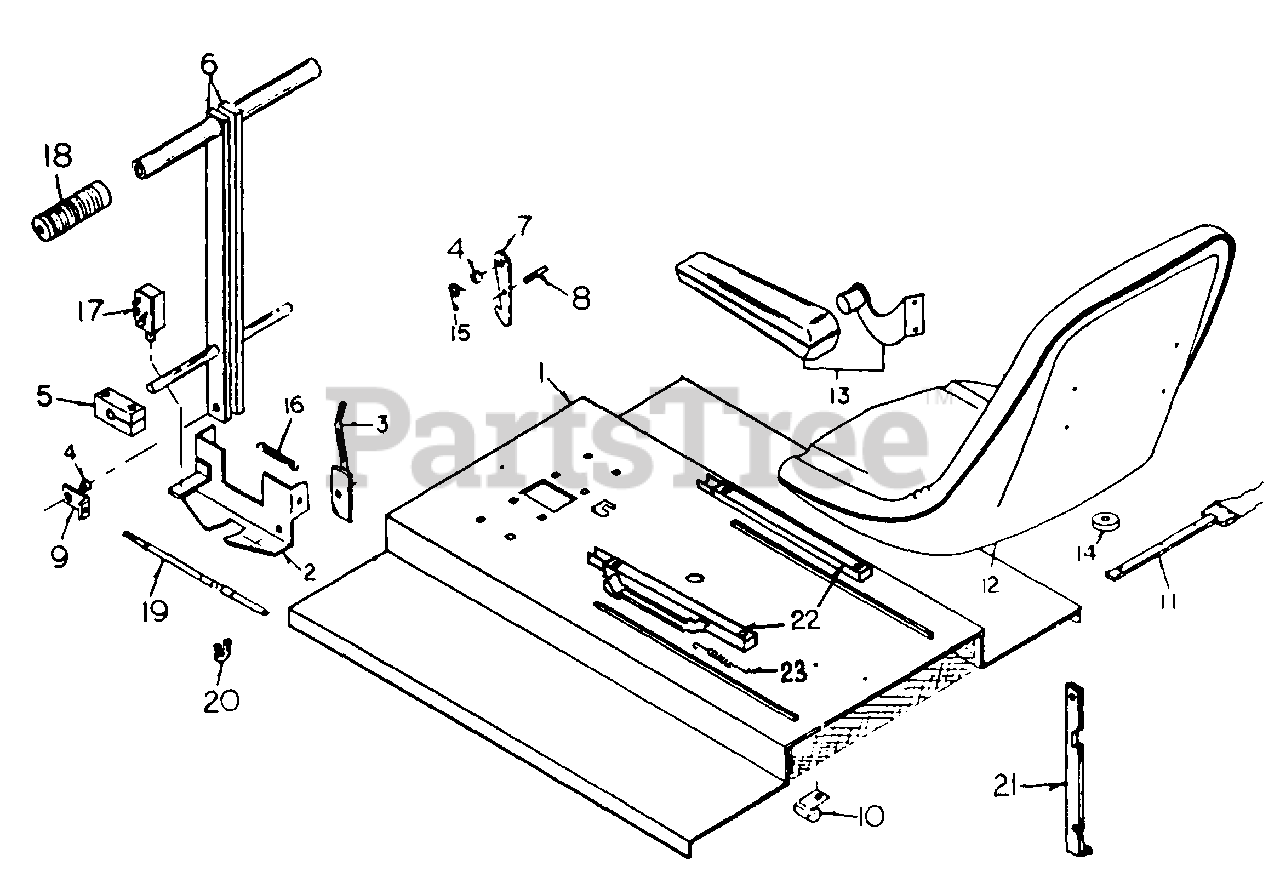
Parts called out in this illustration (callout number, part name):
3	Latch, Lever Lock
4	Bushing
6	Steering Lever
7	Seat Lid Latch
8	Seat Lid Latch Bolt
9	Steering Cable End
10	Seat Lid Harness Retainer
13	Arm Rest Kit
15	Seat Lid Latch Spring
16	Lever Lock Spring
18	Handle Grip
19	Steering Cable
20	Steering Cable Clamp
22	Seat Rail Kit (Pair)
